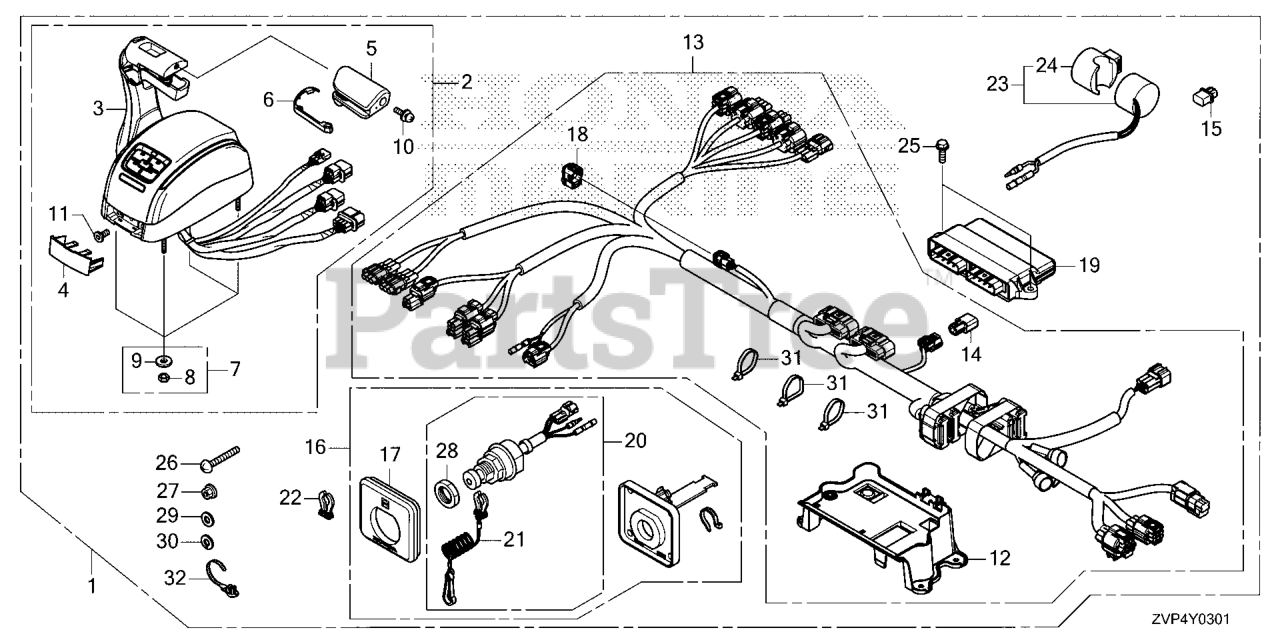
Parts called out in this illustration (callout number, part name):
1	BOX KIT (TWIN-2ND)
2	BOX ASSY., REMOTE CONTROL (TOP MOUNT SINGLE)(RH)
3	CONTROL HEAD
4	COVER CAP
5	GRIP
6	GRIP PLATE
7	NUT SET, MOUNTING
8	NUT
9	WASHER
10	PAN HEAD SCREW
11	SOCKET HEAD CAP SCRE
12	CASE, CONTL UNIT
13	CASE (TWIN-2ND)
14	TERMINATOR ASSY.
15	DUMMY, WATERPROOF CONNECTOR
16	PANEL ASSY., EMERGENCY STOP
17	PANEL, EMERGENCY STOP SWITCH
18	CAP, DUMMY (WPC 4P 090 M) (RED)
19	UNIT ASSY., CONTL
20	SWITCH ASSY., EMERGENCY STOP
21	WIRE, EMERGENCY
22	CLIP, EMERGENCY LOCK
23	BUZZER ASSY., WARNING
24	SUSPENSION, WARNING BUZZER
25	BOLT, FLANGE (6X20)
26	SCREW, PAN (5X40) DUAL QTY = (8) (SINGLE)
27	NUT, FLANGE (5MM)
28	NUT
29	WASHER, PLAIN (5MM)
30	WASHER, SPG (5MM)
31	BAND, SELF-LOCK Use from Frame SN 3000253.
32	CLIP, BAND HARNESS (152.4MM) (BLACK)
